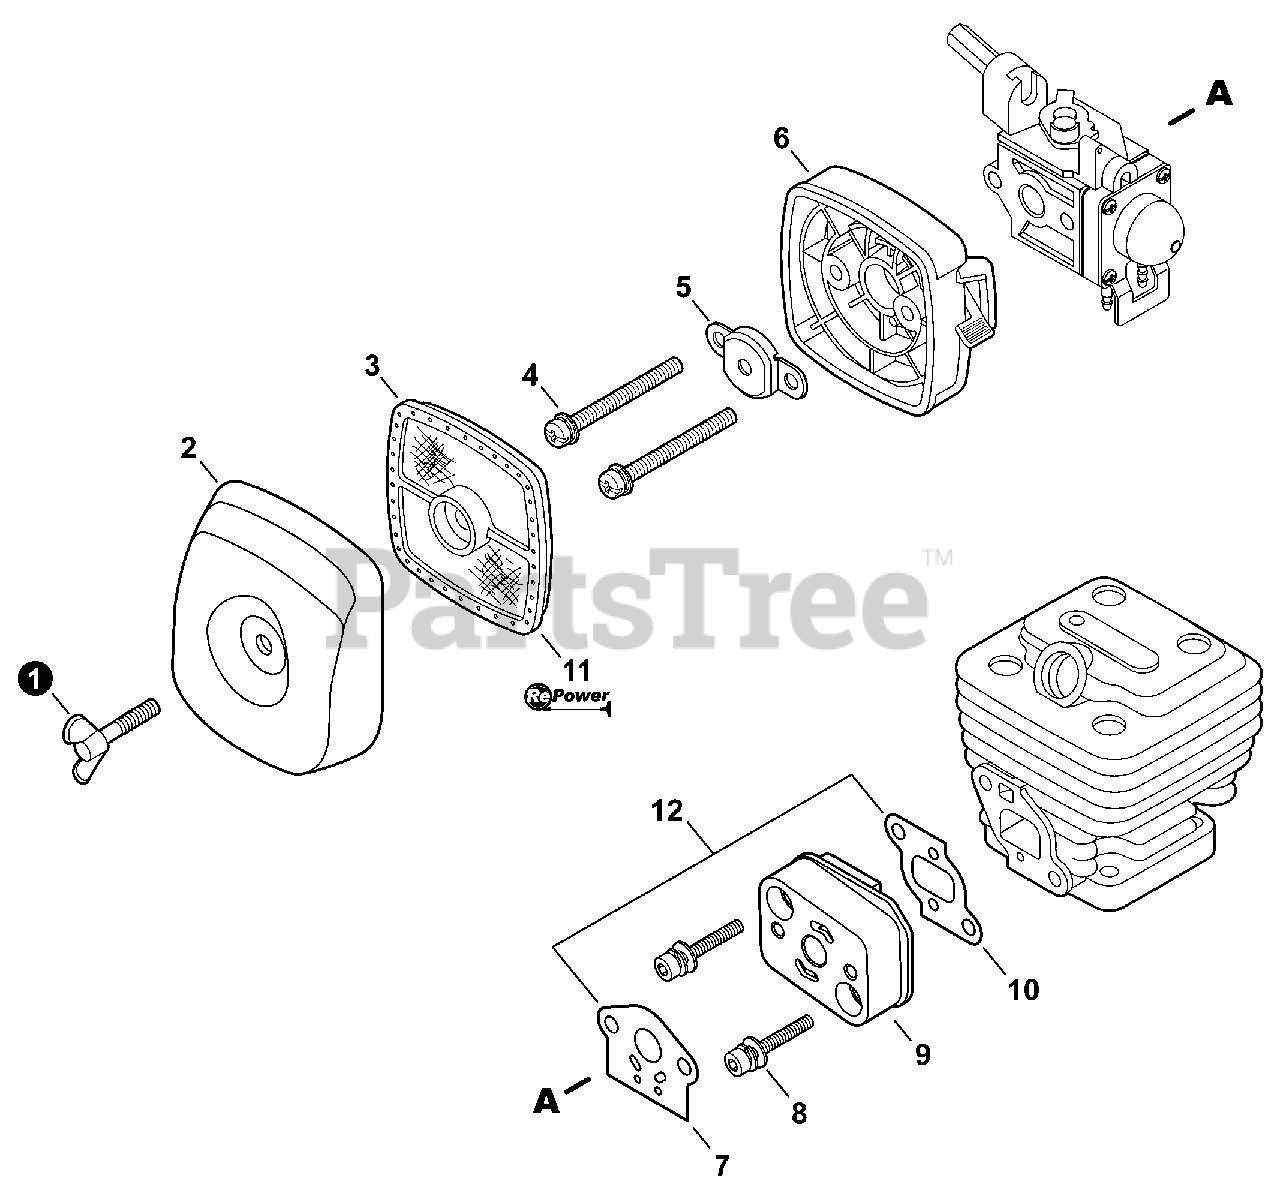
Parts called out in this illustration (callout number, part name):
1	BOLT, WING 5×20
2	COVER, AIR FILTER - BLACK
3	FILTER, AIR - DOUBLE LAYER
4	SCREW 5×60
5	PLATE, PREVENT
6	CASE, AIR FILTER
7	GASKET, CARBURETOR
8	BOLT 5×25
9	INSULATOR, INTAKE
10	GASKET, INTAKE
11	TUNE-UP KIT - REPOWER
12	GASKET KIT
